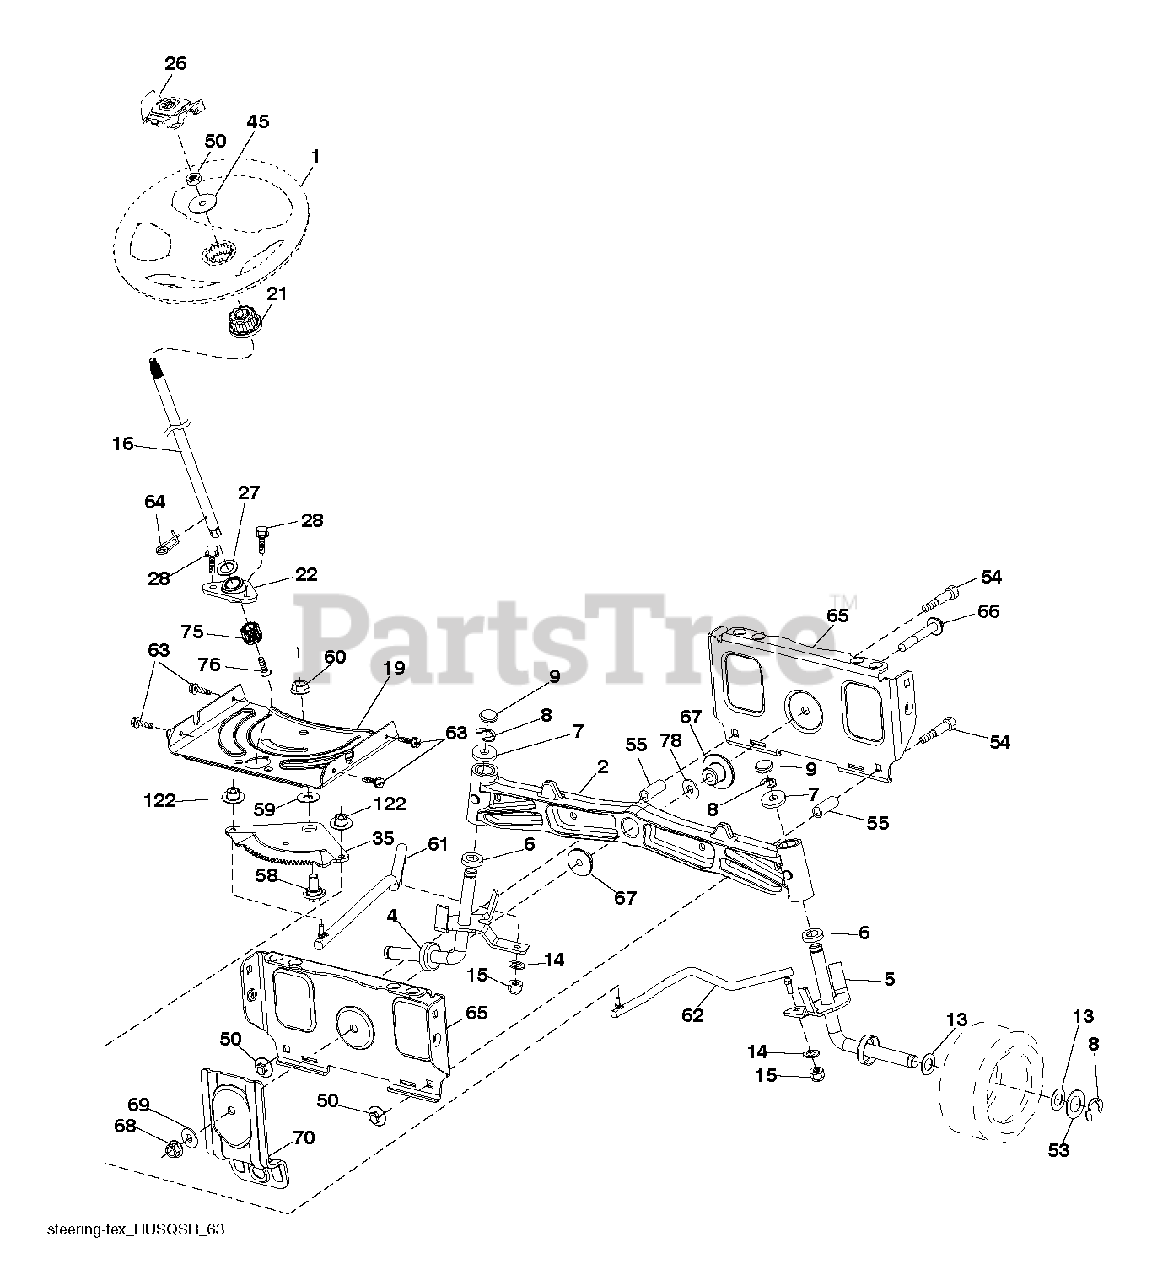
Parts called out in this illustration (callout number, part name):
1	WHEEL.STEER.HUSQ.SR.498.OVMLD
2	AXLE.CAST.IRON
4	SPINDLE.WELDED.LH.16"TEX
5	SPINDLE.WELDED.RH.16"TEX
6	THRUST WASHER
9	CAP.SPINDLE.BLACK
14	WASHER, LOCK 3/8
15	NUT CROWNLOCK 3/8-24
16	SHAFT.STEER.2HIGH.SPLND.PLATED
19	PLATE.STEER.DDL.NLT/NG
21	ADAPTER.WHEEL.STEER.SPLND.ALUM
22	BEARING.SHAFT.STEER.LOWER.625
26	INSERT.CAP.WHL.STRG.HUSQ.PREM
27	WASHER LT
28	SCREW, 3/8-16X3/4
35	GEAR.SECTOR.PLATE.DDL.
45	WASHER.3/8ID.2-3/8OD.12GA.PLTD
50	NUT LOCK FLG 3/8-16 UNC
53	WASHER.HARDENED
55	SPACER.BRACE.AXLE
58	BOLT.SHOULDER.SECTOR.P
59	WASHER.THURST.SECTOR.S
60	NUT FLANGE LOCK 5/8-11
61	DRAGLINK.LH.BALLSTUD.D
62	DRAGLINK.RH.BALLSTUD.D
63	SCREW
64	RETAINER.CLIP.SPRING.S
65	BRACE.AXLE.FRONT.NLT/N
66	BOLT HEX FGHD 7/16-14 X 3 SERR
67	BUSHING.PM.FRONT AXLE
68	NUT.LOCK.FLANGE.7/16
69	WASHER.1.5X.505X.118
70	BRACKET.FRT.DECK.SUSP.RR.MT431
75	PINION.ZINC PLATED
76	SCREW HEAD SOCKET LRVB
78	THRUST WASHER
122	CAP.GEAR.SECTOR.TEX
